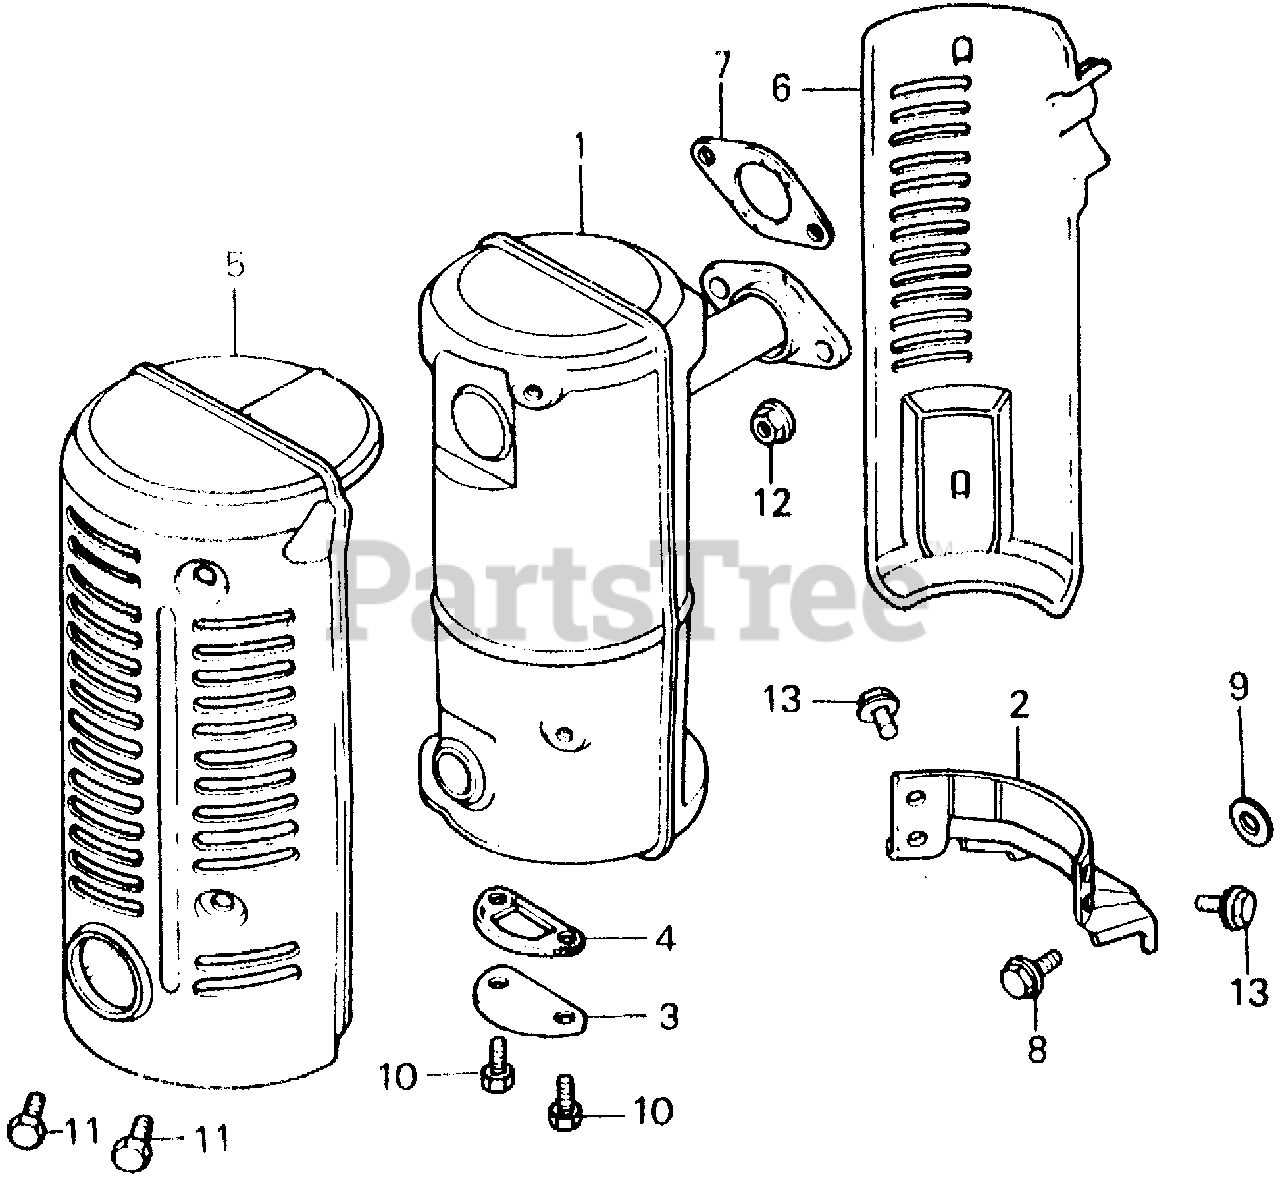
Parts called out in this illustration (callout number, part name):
1	MUFFLER ASSY.
2	STAY, MUFFLER
3	LID, MUFFLER
4	GASKET, MUFFLER LID
5	PROTECTOR A, MUFFLER
6	PROTECTOR B, MUFFLER
7	GASKET, MUFFLER
8	BOLT, FLANGE (8X16)
9	WASHER (8MM)
10	BOLT, HEX. (6X12)
11	BOLT, HEX. (6X6)
12	NUT, FLANGE (8MM)
13	BOLT, FLANGE (6X10)
